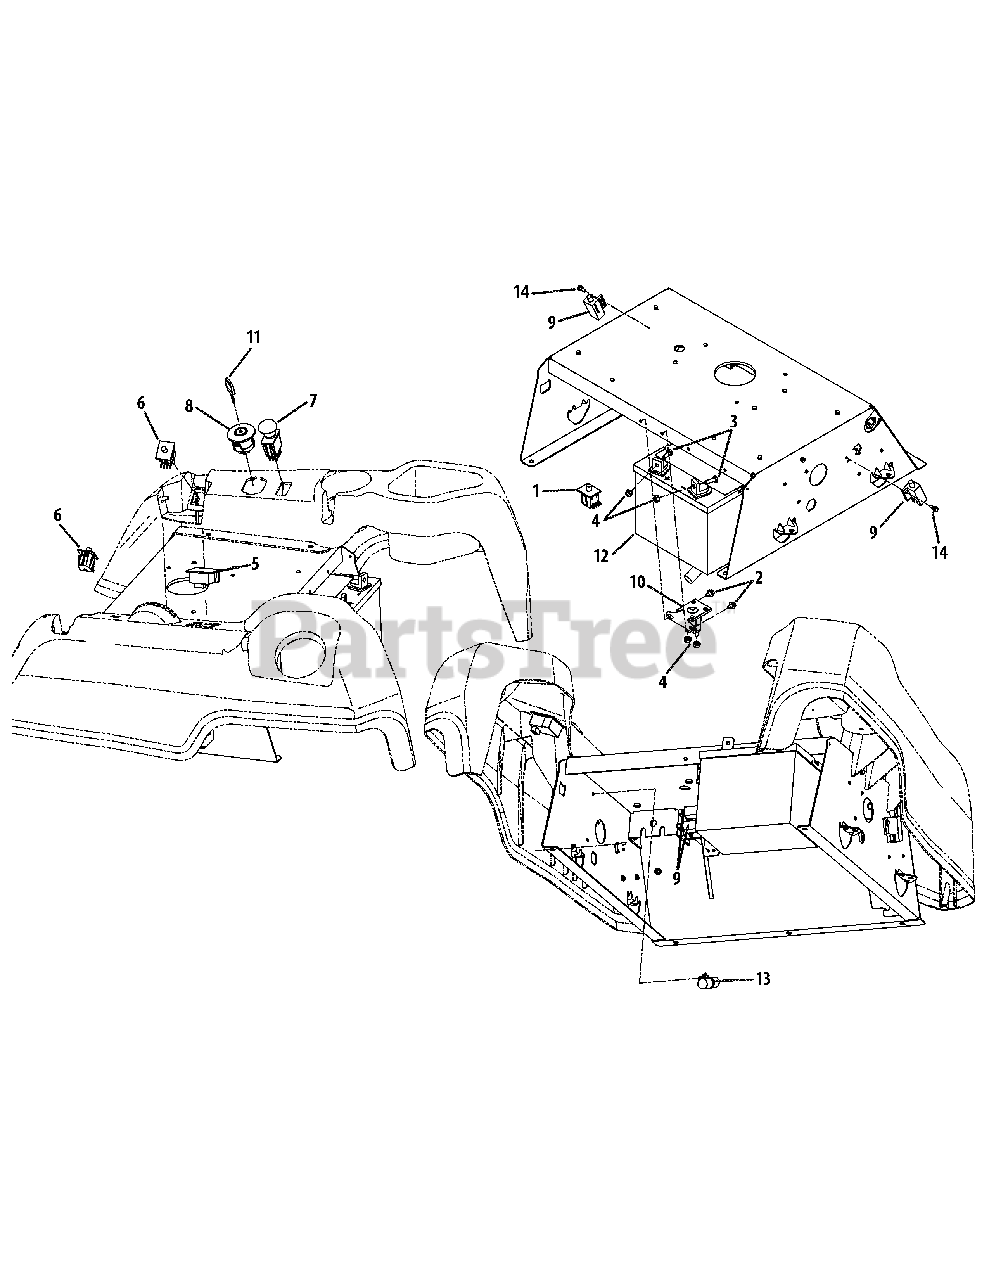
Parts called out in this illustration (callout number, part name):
1	Seat Switch
2	Hex Washer Screw, 1/4-20 x .375
3	Hex Screw, 1/4-20 x .75
4	Hex Nut, 1/4-20
6	Double Pole Neutral Switch
7	PTO Switch
8	Ignition Switch
9	Brake/Reverse Interlock Switch
10	Solenoid
13	Cable Tie
14	Shoulder Screw, #10-32 x .5
